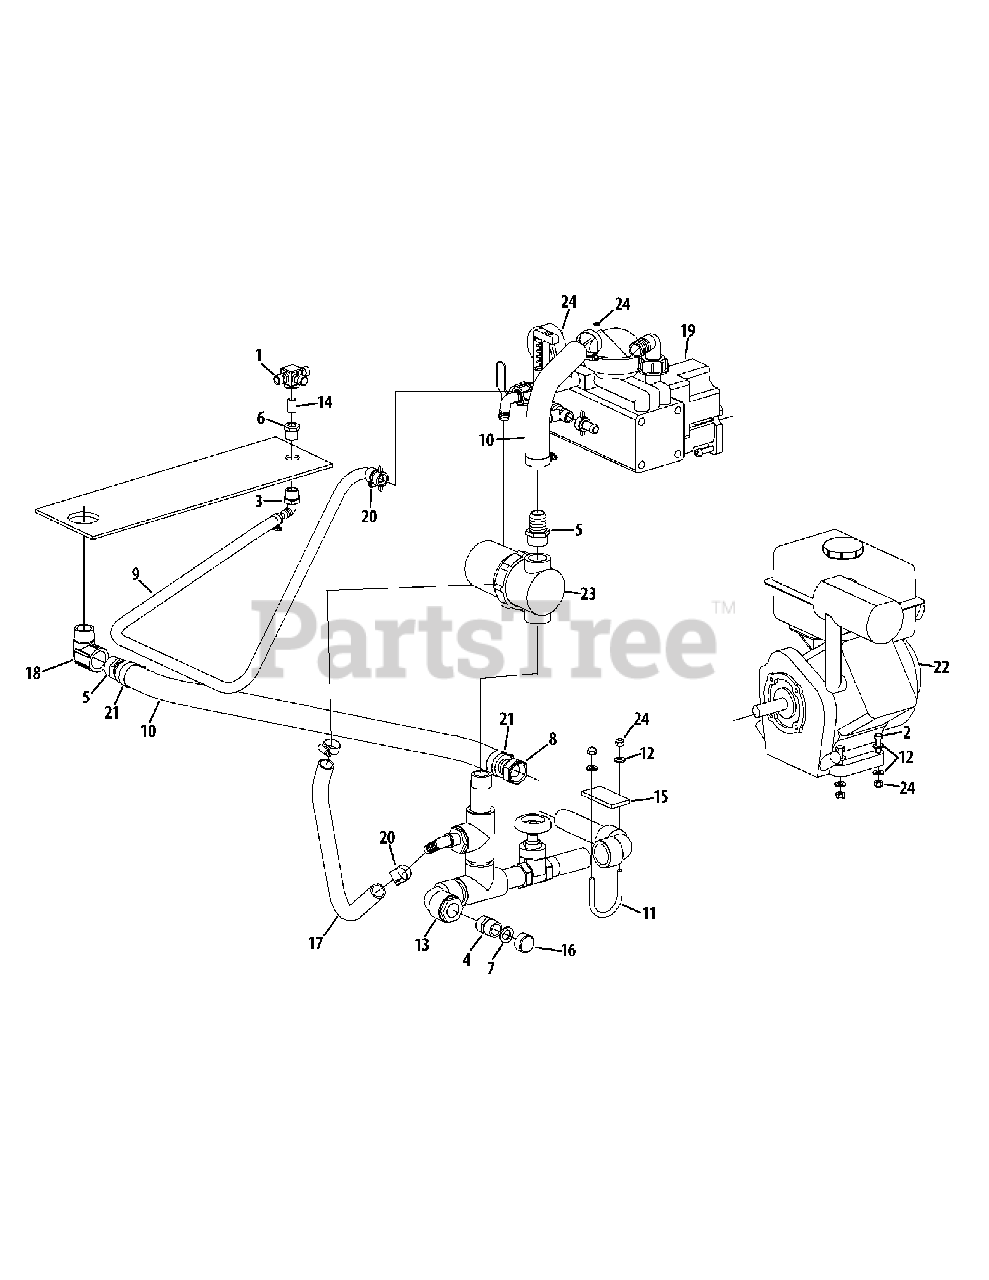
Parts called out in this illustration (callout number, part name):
1	Jet Agitator
2	Hex Screw, 5/16-18 x 1.75
3	90° Elbow, 1/2 x 1/2
4	Threaded Pipe Hose, 3/4 x 3/4
5	Insulated Male Hose, 1 x 1
6	Reducer Bushing, 1/2 x 1/4
7	Hose Washer, 3/4
8	Female Hose Repair End, 1
9	Hose, 1/2
10	Spirafl ex Hose, 1
11	Carriage Bolt, 5/16-18 x 2.62 x 2.30
12	Washer, .344 x .688 x .063
13	Manifold Assembly, 100/200/300
14	Brass Nipple, 1/4
15	Rubber Pad, 1/4 x 1-1/2 x 3
16	Brass Hose Cap, 3/4
17	Reinforced Hose, 5/8
18	Elbow, 1 x 90
19	Pump Assembly
20	Hose Clamp
21	Hose Clamp
22	Kawasaki Engine
23	Mesh Bowl Strainer
24	Hex Lock Nut, 5/16-18
